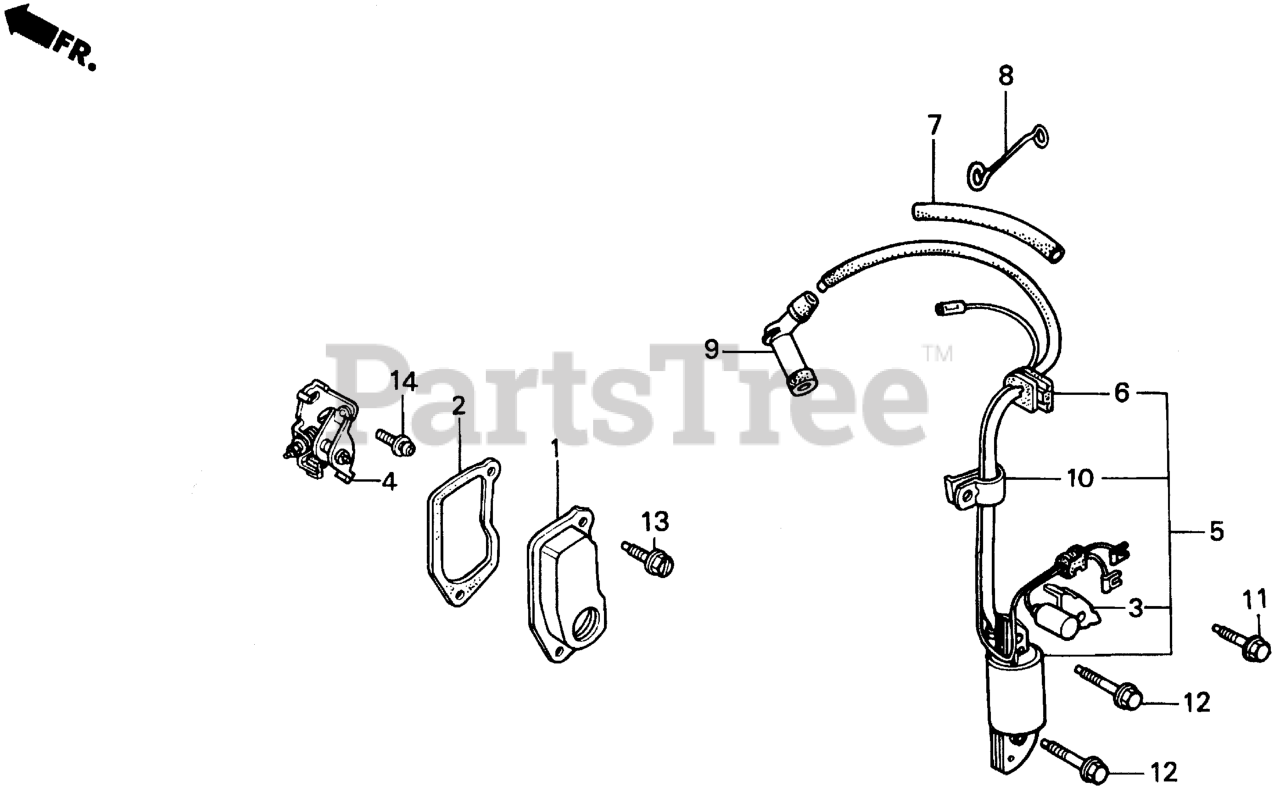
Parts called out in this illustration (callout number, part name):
1	COVER, POINTS
2	GASKET, BREAKER COVER (NOT AVAILABLE)
3	CONDENSER
4	POINTS ASSY.
5	COIL ASSY., IGNITION
6	GROMMET, WIRE
7	TUBE, IGNITION RUBBER
8	CLAMP, IGNITION TUBE
9	CAP ASSY., NOISE SUPPRESSOR
10	CLAMP, IGNITION WIRE
11	BOLT, FLANGE (6X12) (CT200)
12	BOLT, FLANGE (6X32)
13	BOLT, FLANGE (5X10)
14	SCREW-WASHER (5X12)
